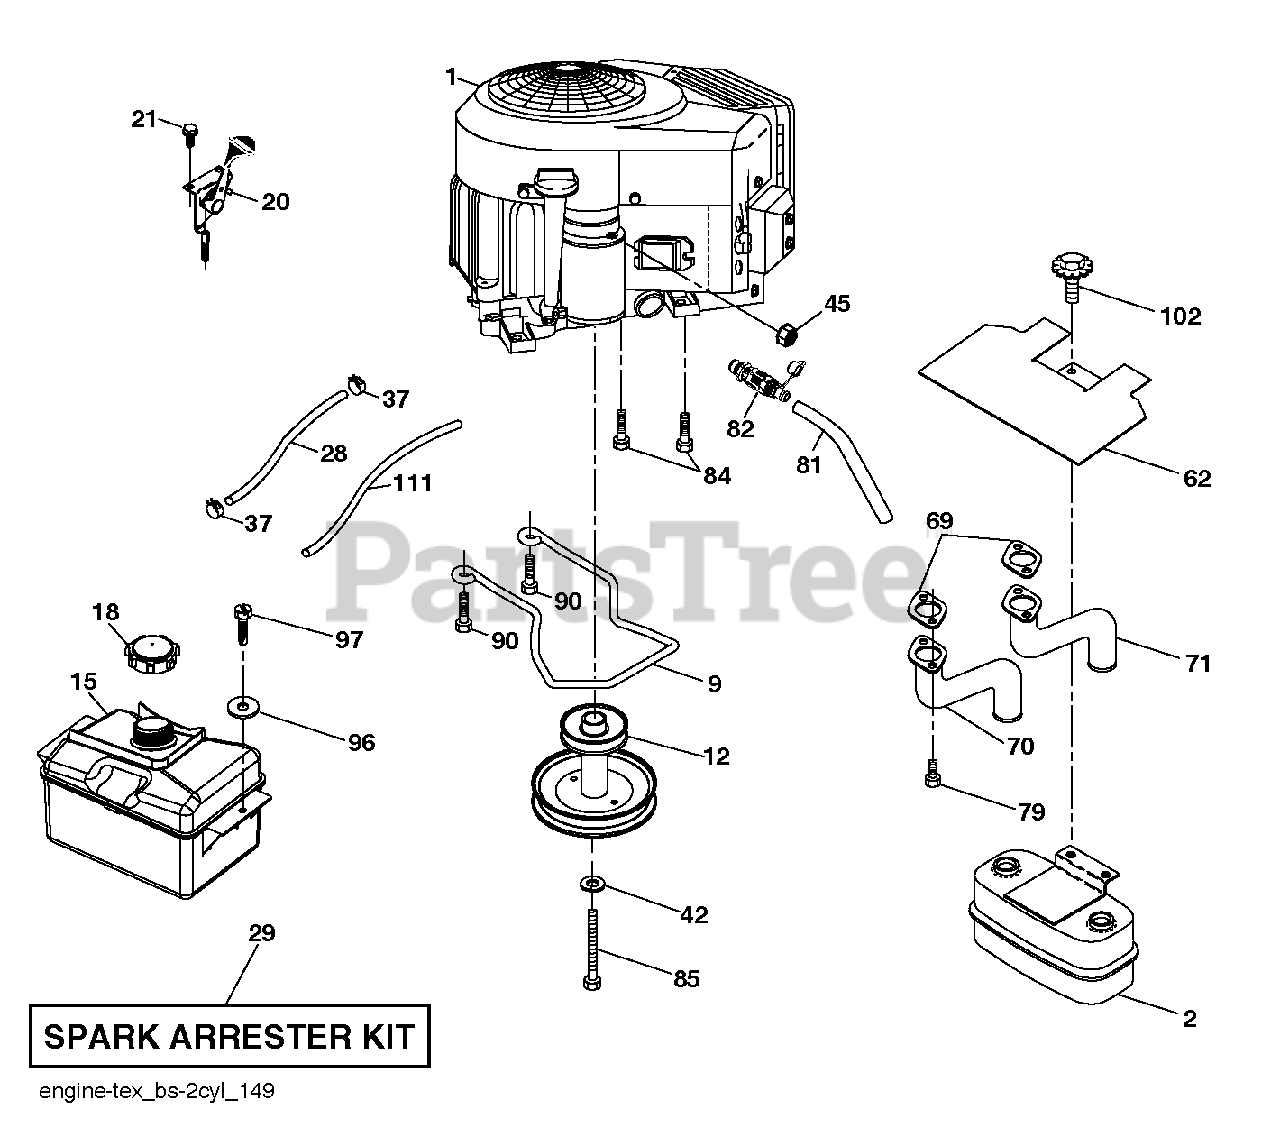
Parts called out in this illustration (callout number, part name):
2	Muffler Assembly, Twin MN
9	KEEPER.BELT.ENG.4.25"2.BLT.431
12	PULLEY.ENGINE
15	Front Tank Assembly, 2.5 Gallon
18	FUEL.CAP.ASM.2.25TETHRED.RATCH
20	CONTROL.TH/CK.COBRA.B&S.TWN.
21	SCREW.#10 X 0.750.BOS
28	LINE.FUEL.20"FRONT.EMI
29	KIT.SPARK ARRESTOR 794945 B&S
37	HOSE CLAMP
42	WASHER 7/16 LOCK
45	NUT
62	SHIELD.HEAT.MUFFLER
69	GASKET.MUFFLER
70	EXHAUST.TUBE.LH.BS/TWIN
71	EXHAUST.TUBE.RH.B&S.TWIN.INTEK
79	SCREW.SOCKET.HEAD.5/16-18
81	TUBE, DRAIN OIL ASM.
82	VALUE.OIL.DRAIN
84	SCREW.3/8-16
85	BOLT.HEX.7/16-20X4.GR5.1.5BLUE
90	SCREW 3/8-16X1
97	SCREW HEXWSHR 1/4-20X3/4
102	SCREW
111	RP PURGE LINE
